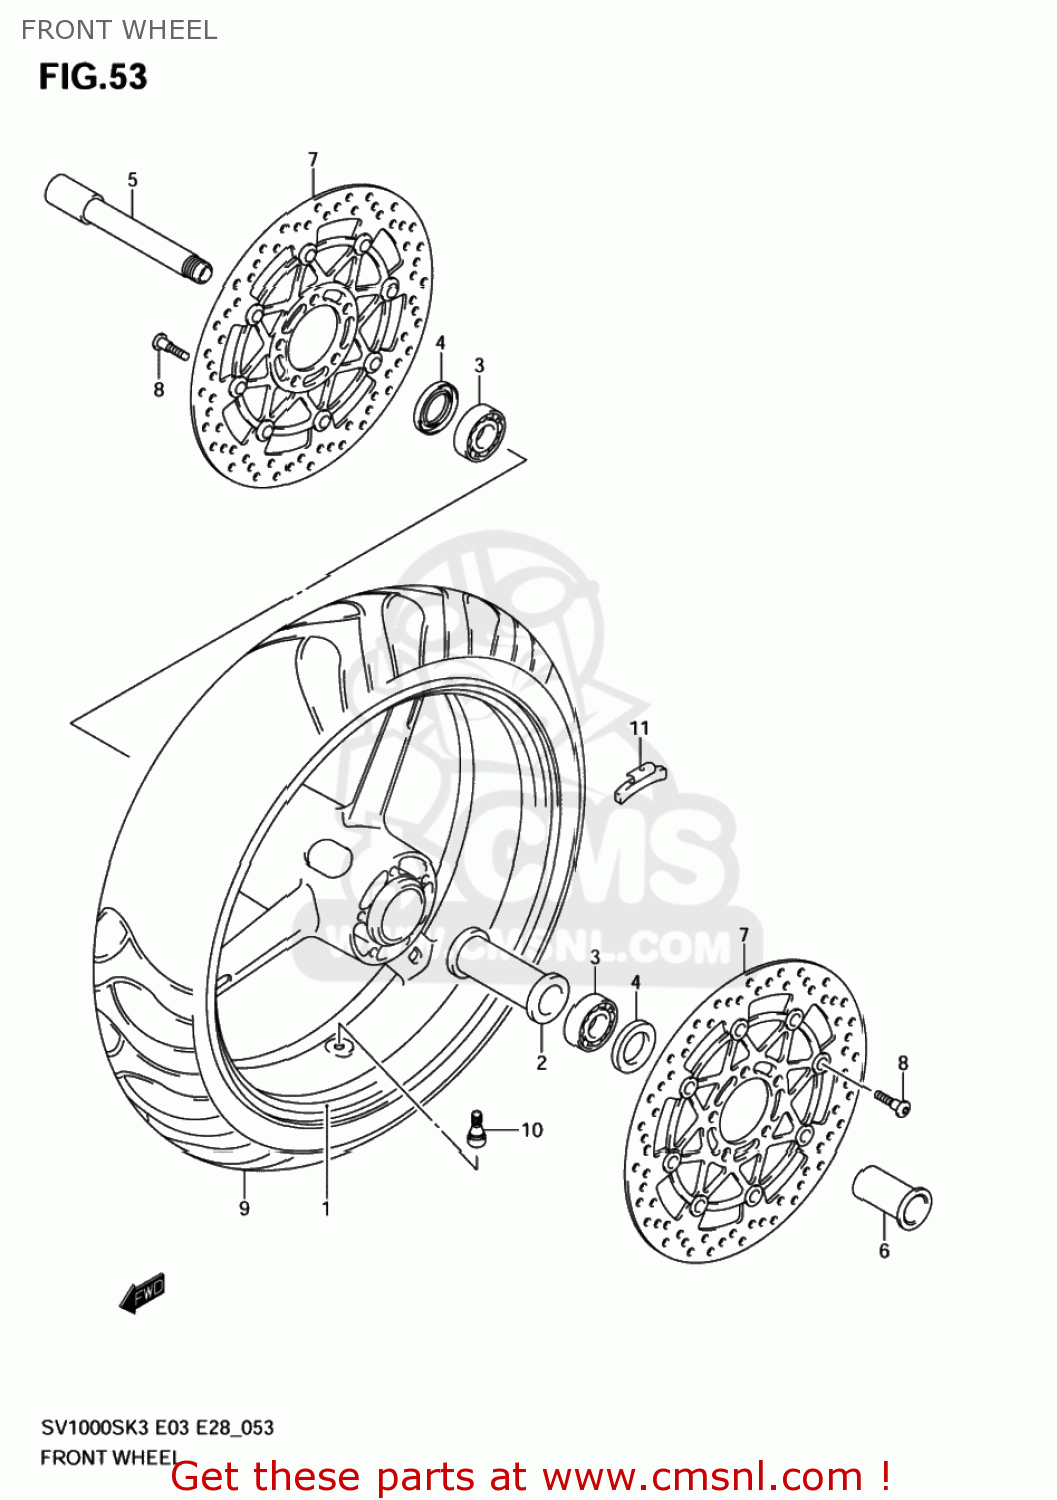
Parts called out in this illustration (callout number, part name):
1	WHEEL,FR(17M/CXMT3.50)
2	SPACER,FRONT HUB BEARING
3	BEARING(25X52X15)
4	SEAL,OIL(32X52X7)
5	AXLE,FR
6	NUT,FR AXLE
7	DISC,FR BRAKE
8	BOLT(8X33)
9	TIRE, FR 120/70 (PURCHASE LOCALLYSV1000K3/K4/K5)
10	VALVE ASSY,WHEEL RIM(TR412)
11	WEIGHT,WHEEL BALANCE 10G
